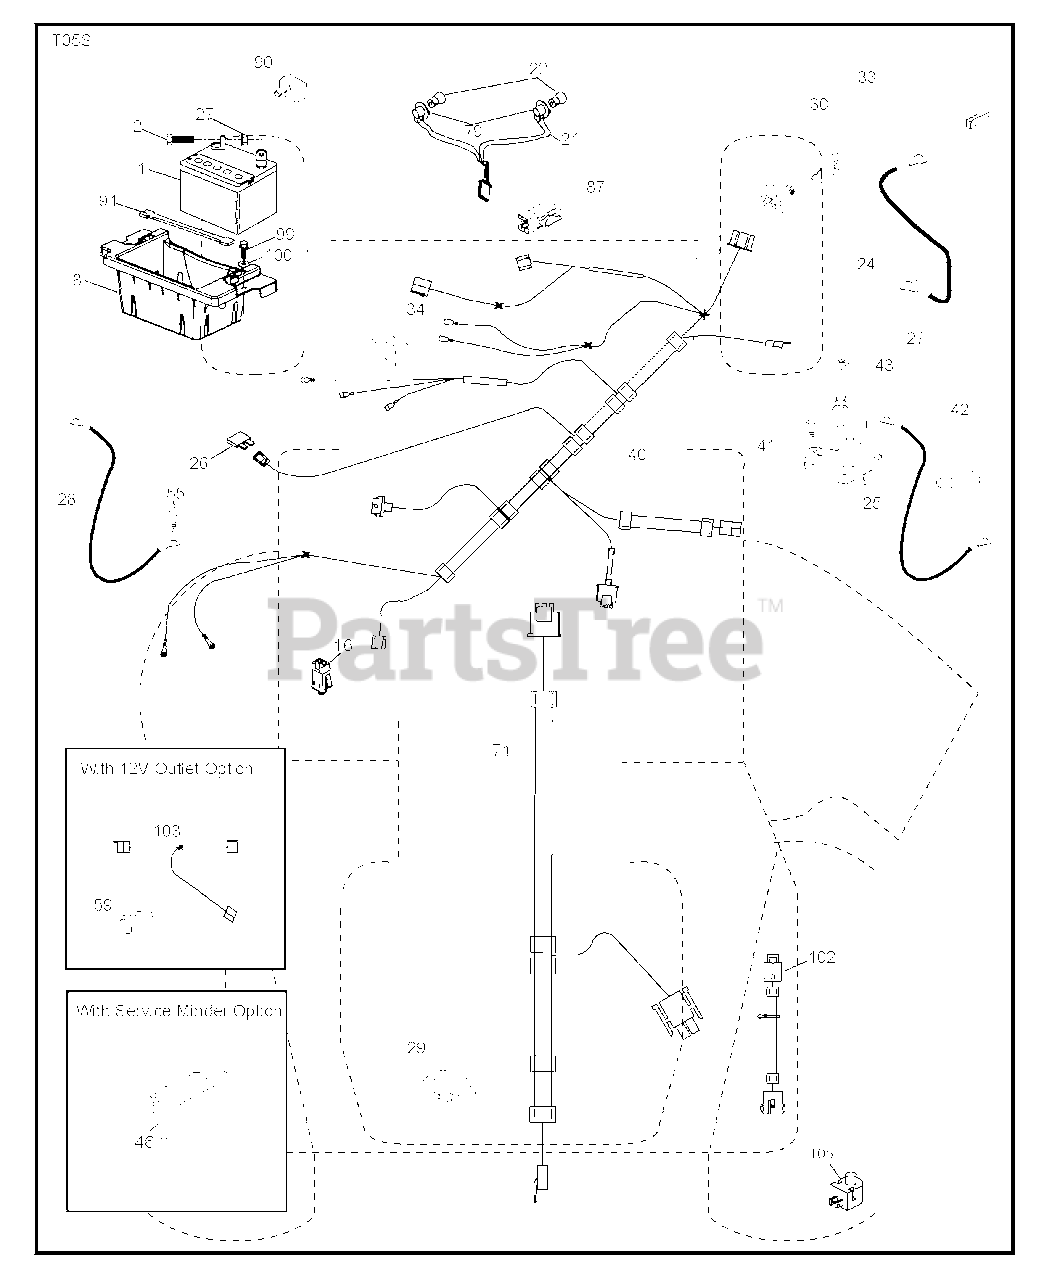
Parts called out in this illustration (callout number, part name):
1	REPL BY 532 12 38-99
8	BOX.BATTERY.MOUNT.FRONT.LT
16	SWITCH INTERLOOK PUSH-IN
21	HARNESS.LIGHT W/4152J BULBS
22	LIGHTBULB
24	CABLE.BATT.POS.WIRE.TG.DA SOL
25	CABLE.STARTER.6G.BL/RED.17.5
26	FUSE 20AMP
27	NUT
28	CABLE GROUND 6 GA 21" 90T BLK
29	SWITCH.SEAT.DELTA.OPC.
30	SWITCH.IGN.DELTA.W.LGH.ROS
33	KEY.CHAIN.BLISTER.PACK.GEN.INT
34	SWITCH LT
40	HARNESS IGN. DASH
41	SCREW
42	TERMINAL COVER
43	SOLENOID.W/BRASS.PLUNG
46	GUAGE.SRVCMNDR.HRMTR.
55	SCREW 5/16"
71	HARNESS-CHASSIS SUB
79	BULB HOLDER ASM.
87	SWITCH.INTRLCK.CLUTCH.
90	COVER.TERMINAL.BATTERY
91	STRAP, BATTERY MOUNT
99	SCREW HEXWSHR 1/4-20X3/4
102	HARNESS PIGTAIL PCH TEX ROS
105	REVERSE SWITCH
